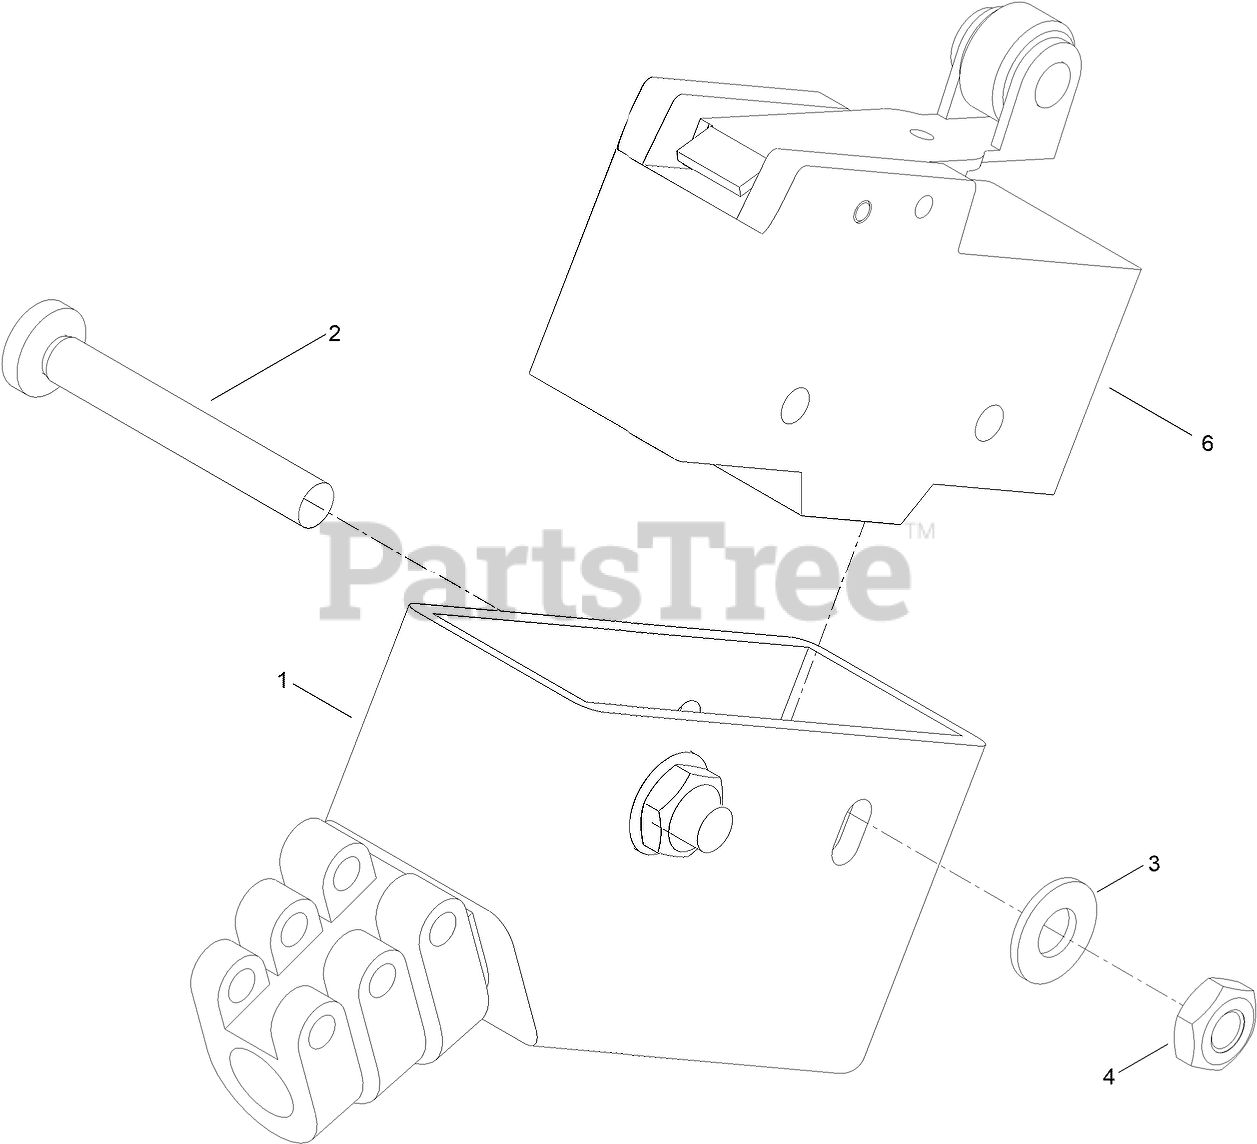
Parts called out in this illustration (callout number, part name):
1	COVER, SWITCH
3	WASHER
6	HOUSING, BRAKING SWITCH
